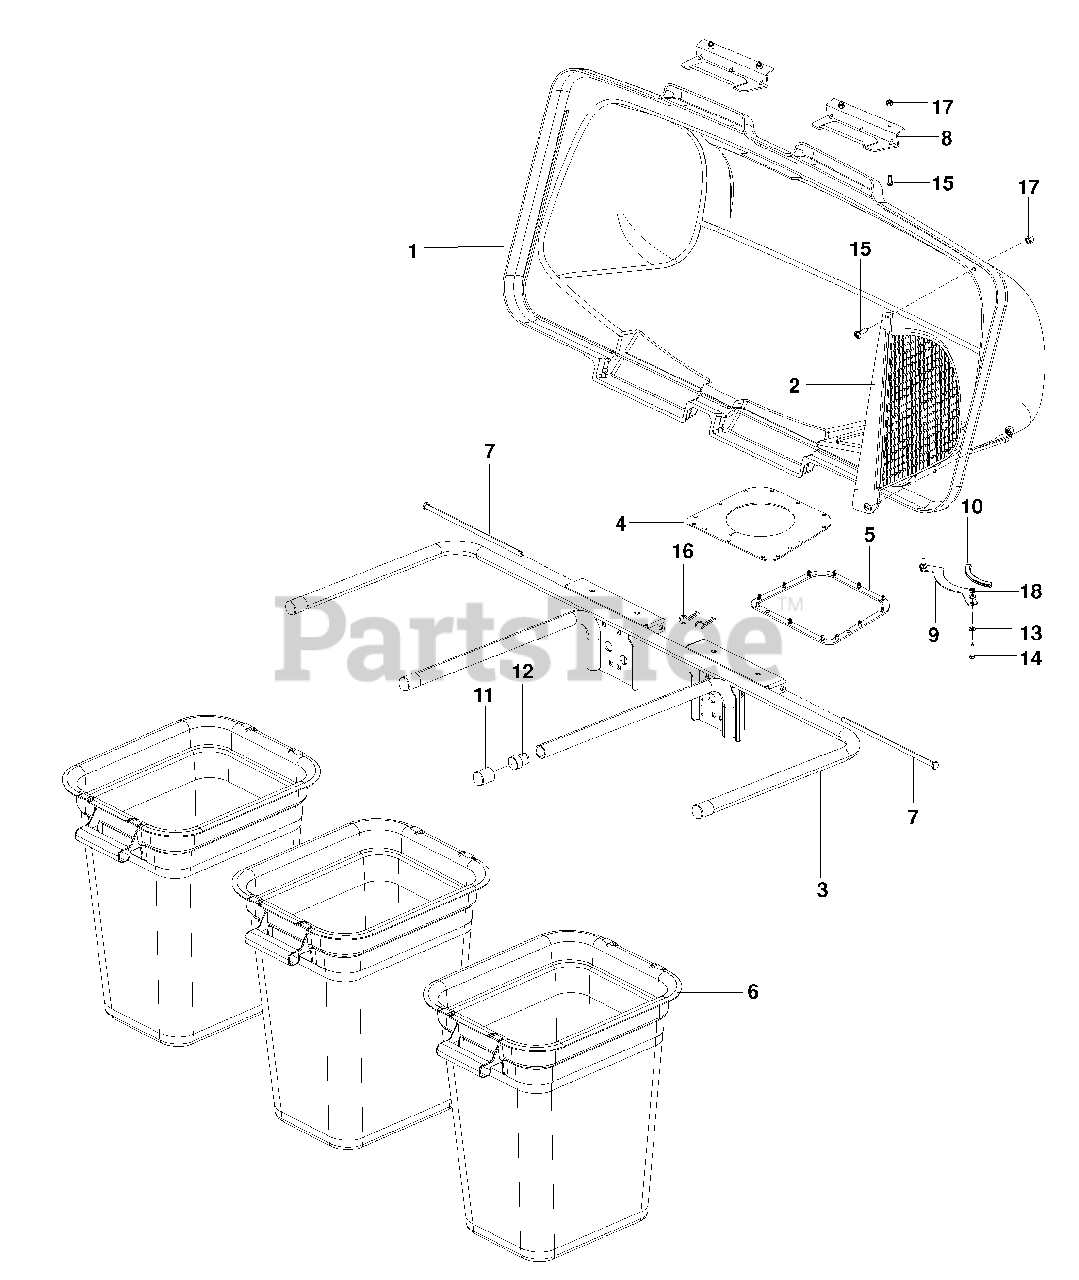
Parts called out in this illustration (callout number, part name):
2	Screen, Cover
3	Frame, Bagger
4	Seal, Cover
5	Gasket, Cover
6	Container, Soft Bag
7	Pin, Hinge
8	Handle, Bagger Cover
9	Support, Hose
10	Flex Trim, Black
11	Plug, Tubing End
12	Plug Spacer
13	Washer 5/16 Sae Flat
14	Hcs 5/16-18 X 11/4
15	Screw #10-24 X 5/8
17	Nut #10-24 Crownlock
18	Nut 5/16-18 Hex Nyloc
